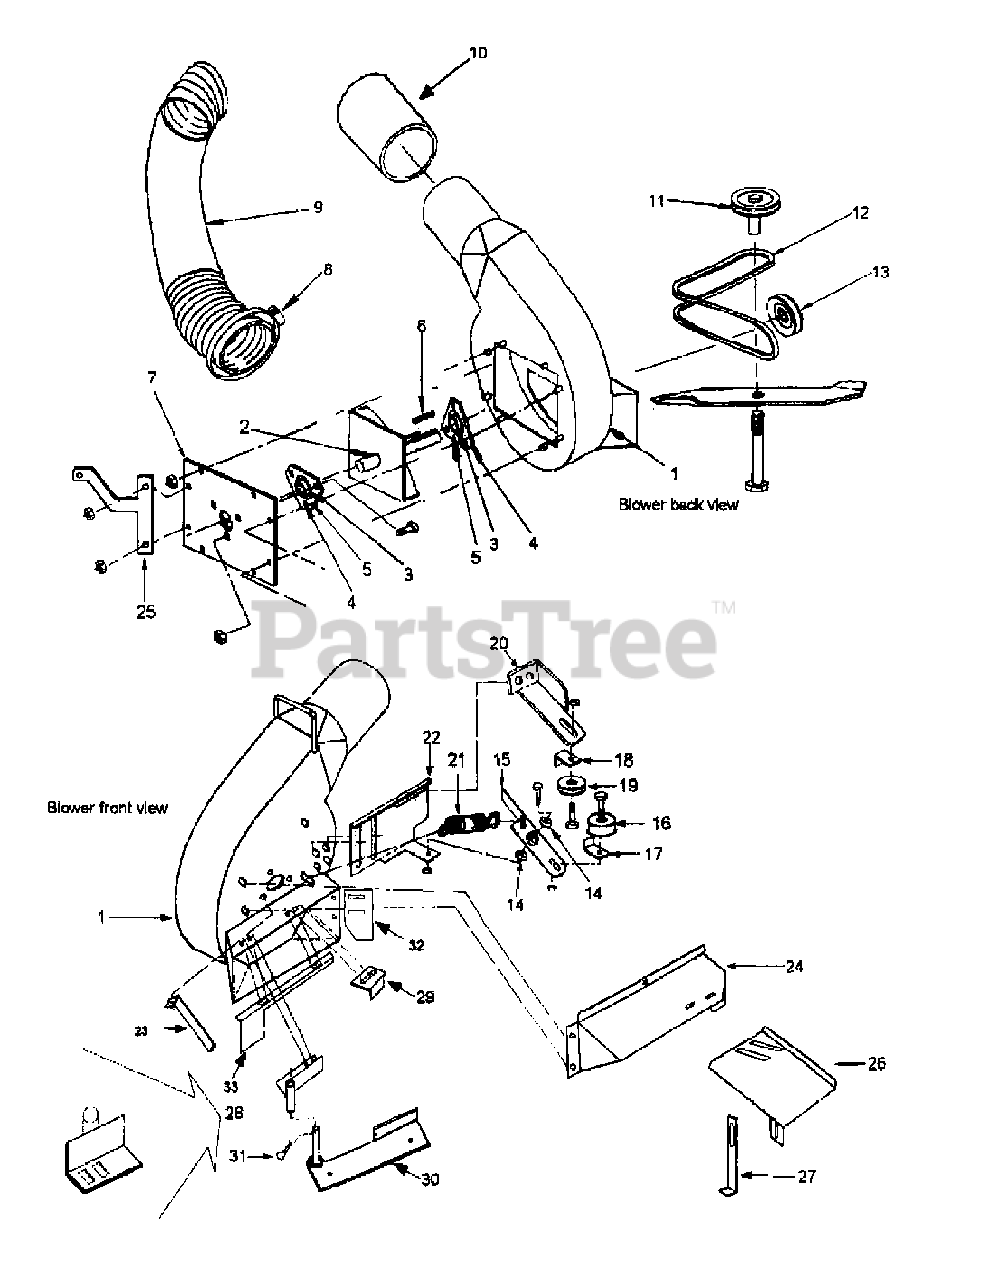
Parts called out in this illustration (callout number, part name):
1	Blower Canister
3	Fan Bearing w/ collar
4	Bearing Flangette w/ grease zerk
5	Bearing Flangette
6	Key 1/4" x 1"
7	Blower Cover Plate
8	6" Hose Clamp
9	6" x 43" Hose
10	6" Hose Insert
11	Deck Pulley
13	Blower Drive Pulley 3.5"
14	Idler Arm Bearing
15	Idler Arm
16	Flat Idler Pulley 3.25"
17	Flat Idler Pulley Bracket
18	V-Idler Pulley Bracket
19	V-Idler Pulley 3.5"
20	V Pulley Bracket
21	Idler Spring
22	Blower Pulley Bracket
23	Fan Pulley Belt Bracket
24	Blower Belt Cover
25	Pulley Bracket Support
26	Belt Guard Leg
27	Belt Guard Leg
28	Blower Mount Front
29	Blower Support Bracket
30	Blower Mount Deck
32	Blower Tab
33	Blower Blocking Plate
